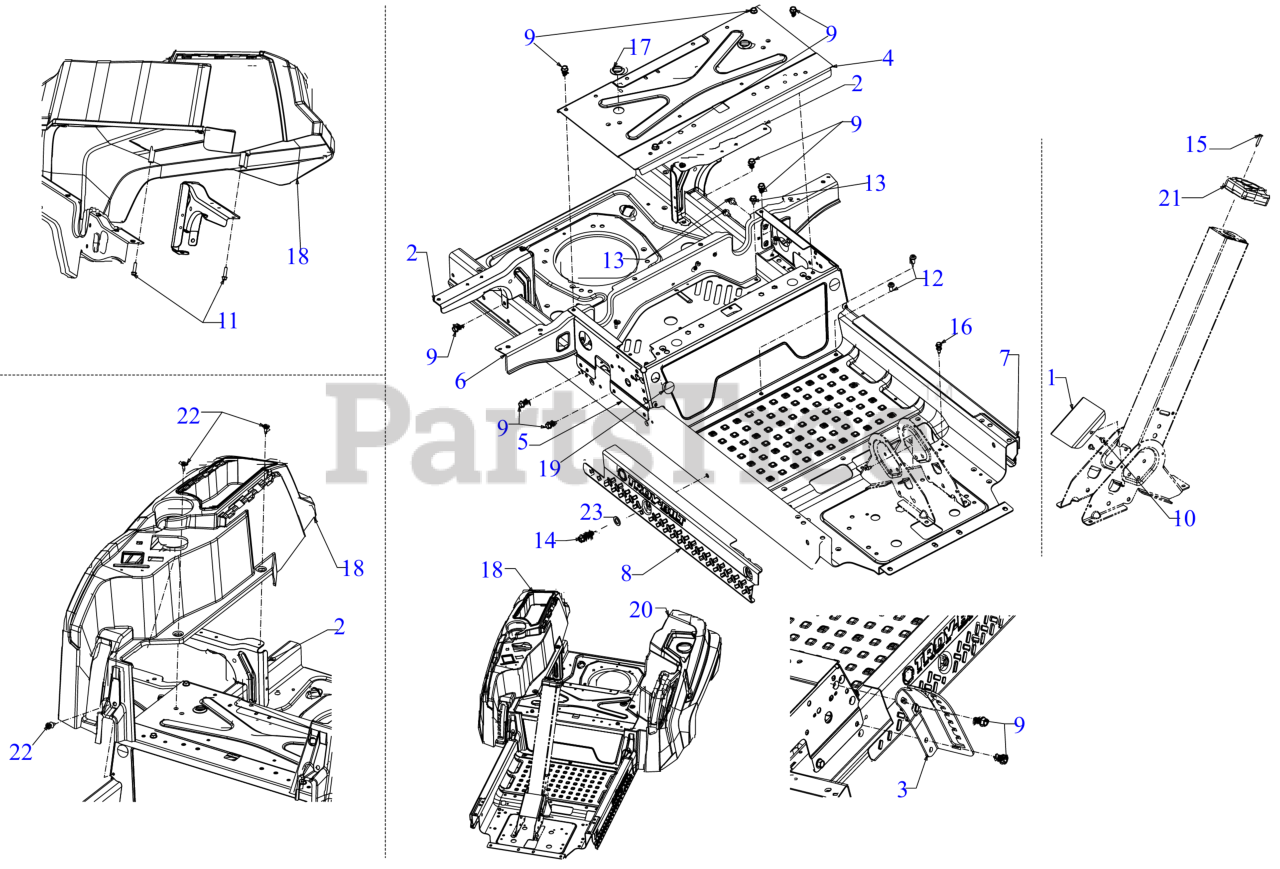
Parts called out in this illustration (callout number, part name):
2	REAR TANK BRACKET
3	HEIGHT INDEX BRACKET
7	FRAME SUPPORT (LH)
9	SCREW 5/16-18 x .750
10	SCREW 1/4-20 x .5
11	SCREW 5/16-14 x 1
12	SCREW 5/16-18 X.75
13	SCREW 5/16-18 x .500
14	SCREW 3/8-16 x 1.25 GR5
15	SCREW #10-16 x 1.25
16	SCREW 1/4-20X.625
18	CONSOLE (RH)
19	PLASTIC PLUG
20	CONSOLE (LH)
21	STEERING COLUMN COVER
22	SHOULDER SCREW M6-1 .368 X.115
23	FLAT WASHER
